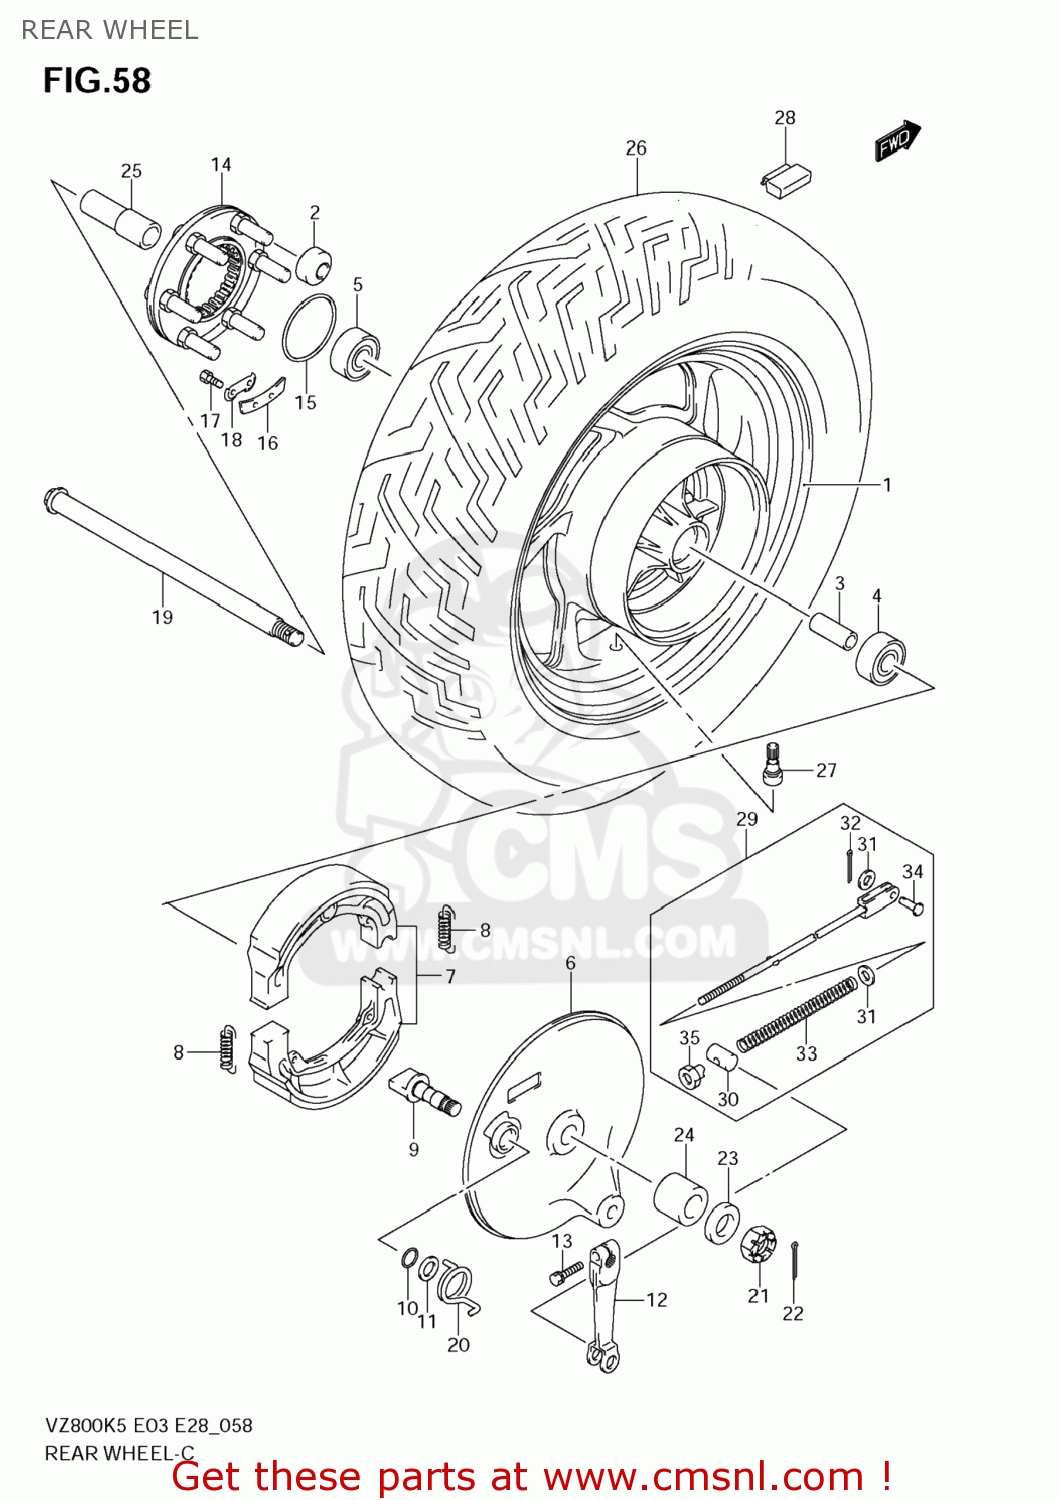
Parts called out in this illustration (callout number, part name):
1	WHEEL,RR(15M/CXMT4.00)
2	BUSH
3	SPACER(17.3X25X99)
4	BEARING
5	BEARING
6	PANEL, REAR BRAKE ANCHOR
7	SHOE SET,BRAKE (NAS)
8	SPRING,BRAKE SHOE
9	CAM,RR BRAKE
10	O RING(D:2.4,ID:14.8)
11	WASHER(15.5X24X1.6)
12	LEVER,RR BRAKE CAM
13	BOLT
14	JOINT ASSY,RR HUB DRIVEN
15	O RING(D:2.1,ID:65)
16	WASHER,THRUST(T:1.6)
17	BOLT(6X16)
18	WASHER
19	AXLE,RR
20	SPRING
21	NUT
22	PIN
23	WASHER(17X30X3.2)
24	SPACER,RR AXLE,R
25	SPACER,RR AXLE,L
26	TIRE,RR(170/80 15M/C 77H)
27	VALVE ASSY,WHEEL RIM(TR412)
28	WEIGHT,WHEEL BALANCE 10G
29	ROD ASSY,RR BRAKE
30	PIN(13X18)
31	WASHER
32	PIN
33	SPRING
34	PIN(L:13.5)
35	NUT
